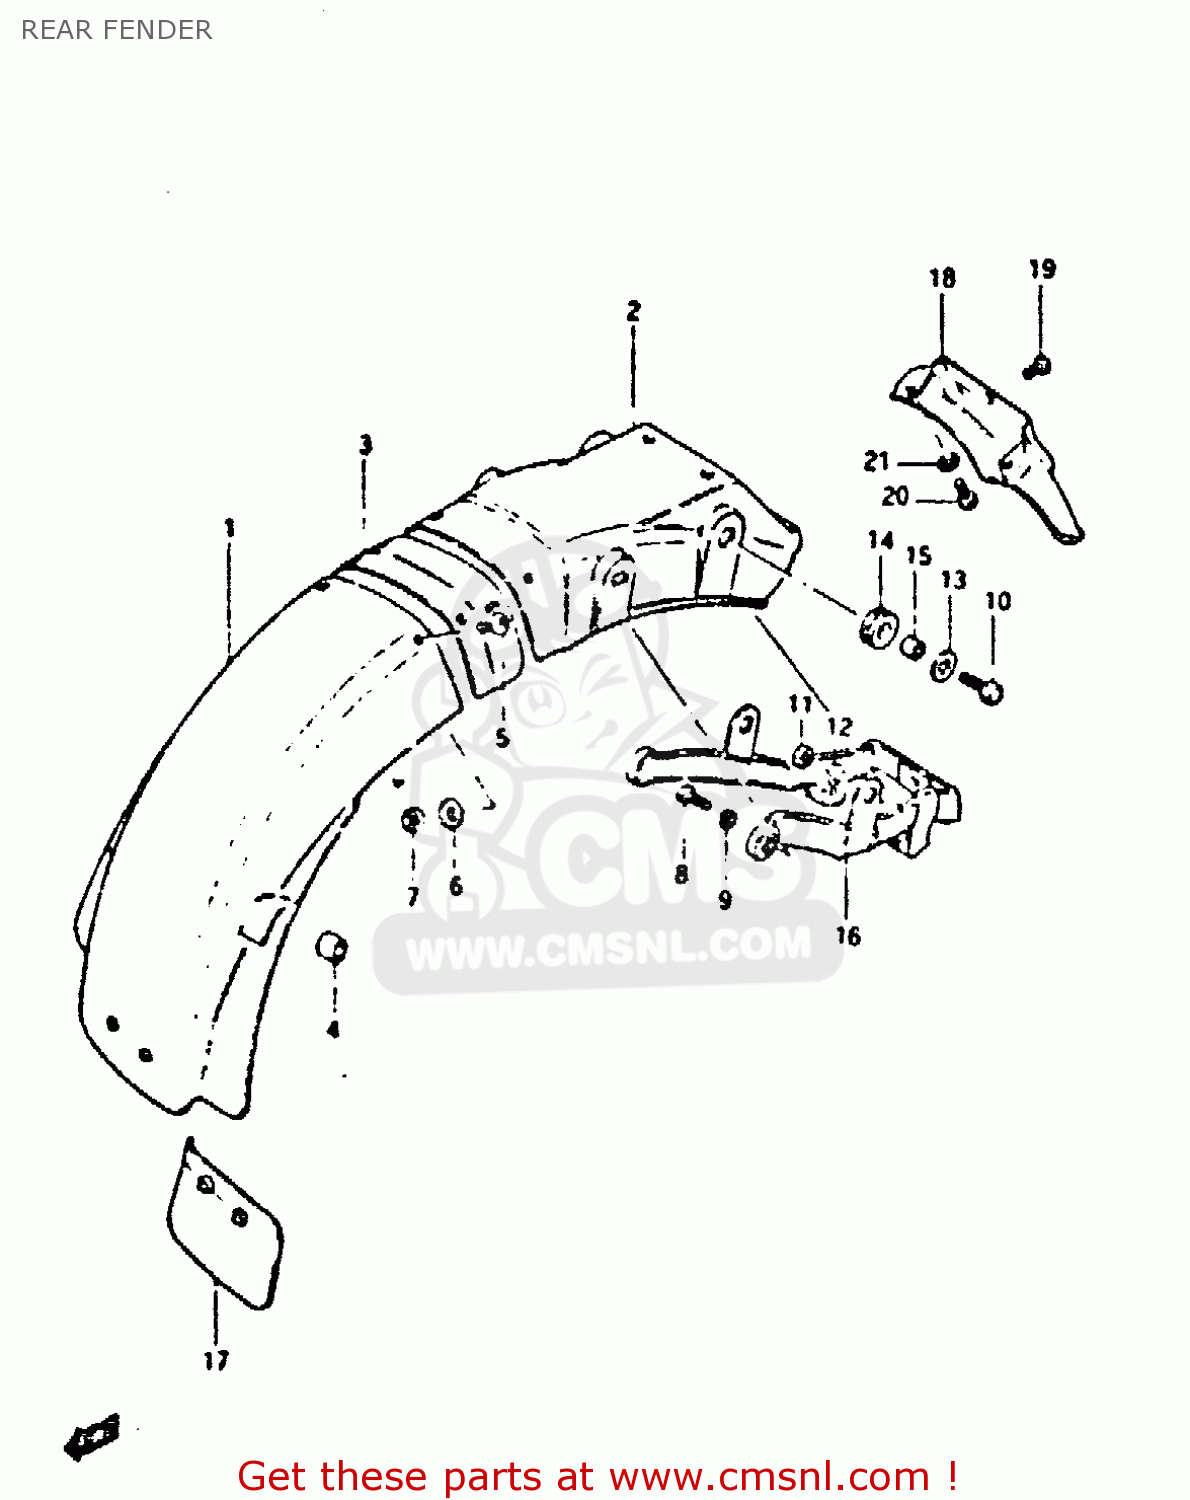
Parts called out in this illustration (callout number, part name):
1	BODY,REAR FENDER,REAR
2	BODY,REAR FENDER,REAR
3	JOINT,REAR FENDER
4	CUSHION
5	SCREW
6	WASHER (5.5X16X1.2)
7	NUT
8	BOLT, UPPER
9	LOCK WASHER
10	BOLT (8X30)
11	NUT
12	LOCK WASHER
13	WASHER
14	CUSHION
15	SPACER (8.2X12X7.5)
16	REINFORCEMENT,REAR FENDER
17	GUIDE,RR FENDER MUD
18	EXTENSION,RR FENDER
19	SCREW
20	BOLT, UPPER
21	WASHER (6.5X20X1.2)
